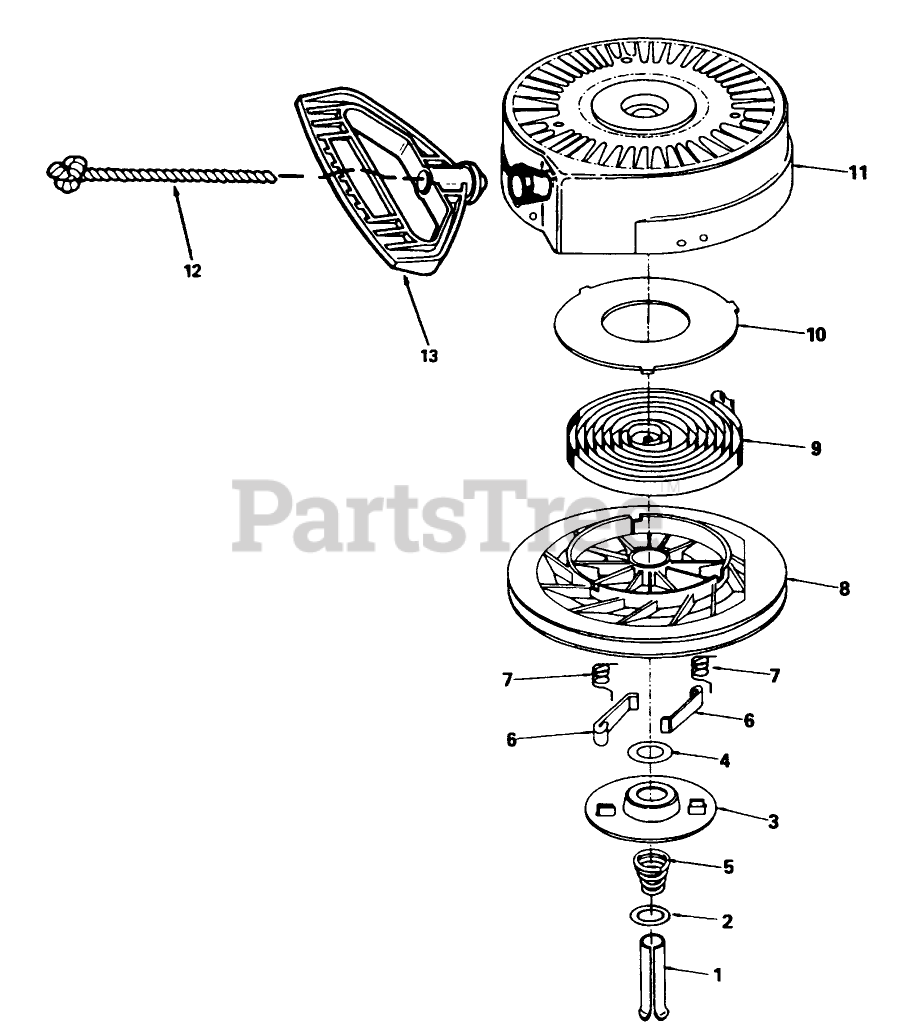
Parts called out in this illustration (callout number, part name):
1	Pin, Spring (Incl. Ref. #7)
2	Washer
3	Retainer
4	Washer
5	Brake Spring
6	Dog-Starter
7	Spring-Dog
8	Pulley and Rewind Spring ASM
9	Rewind Spring
10	Cover-Spring
11	Housing Assembly
12	Rope-Starter (98 cut to length)
13	Handle-Starter, Mitten Grip
